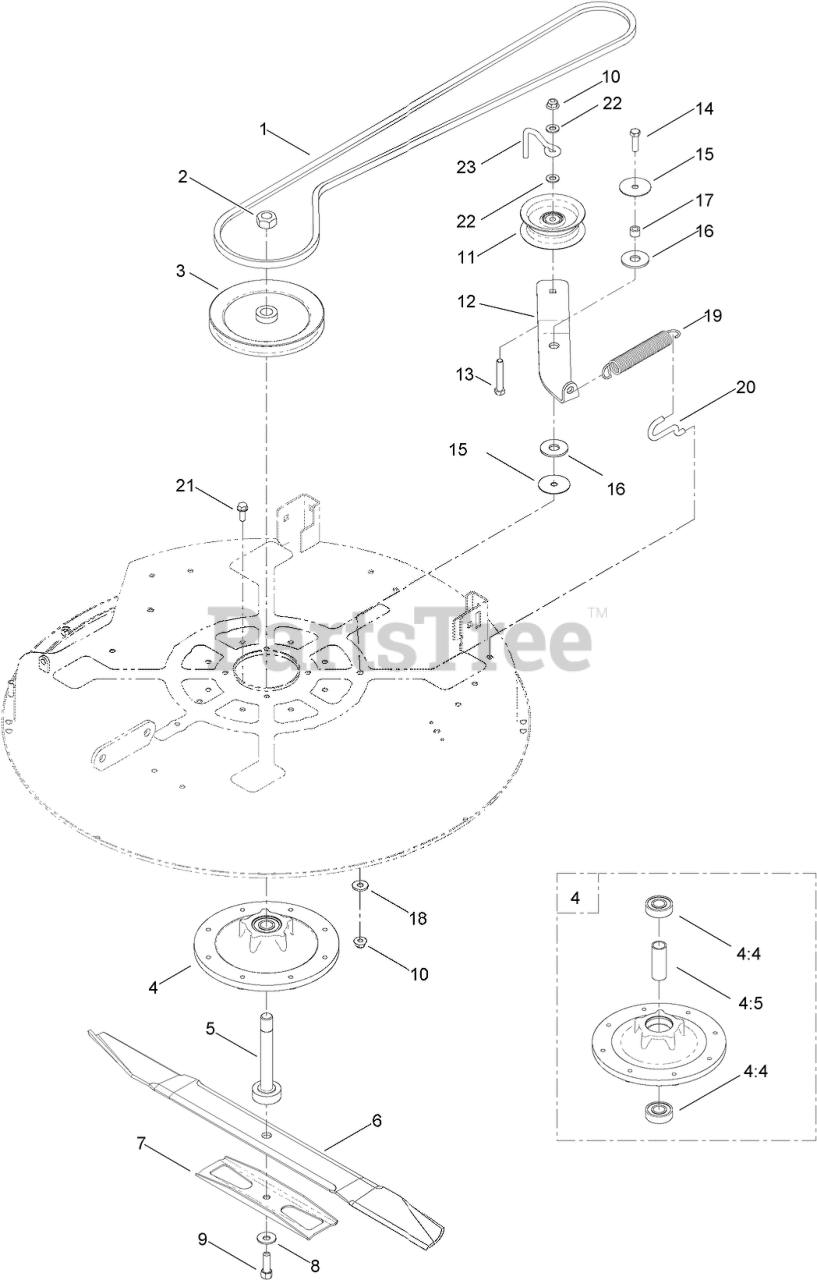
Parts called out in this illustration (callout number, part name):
1	V-BELT, 81.8 INCH
2	NUT-HEX
3	PULLEY-DECK
4	SPINDLE HOUSING ASM
4:4	BEARING-BALL
4:5	SPACER-BEARING
5	SHAFT-SPINDLE
6	BLADE-RECYCLER, 31.35 INCH
7	STIFFENER
8	WASHER-BELLEVILLE
9	SCREW-HH
10	NUT-HF, NI
11	PULLEY-IDLER, FLAT
12	ARM-IDLER
13	SCREW-HH
14	SCREW-HH
15	WASHER
16	WASHER-FRICTION, COMPOSITE
17	SPACER
18	WASHER-HARDENED
19	SPRING-EXTENSION
20	HOOK-RETURN, SPRING
21	SCREW-TAPTITE
22	WASHER-FLAT
23	GUIDE-IDLER, BELT
